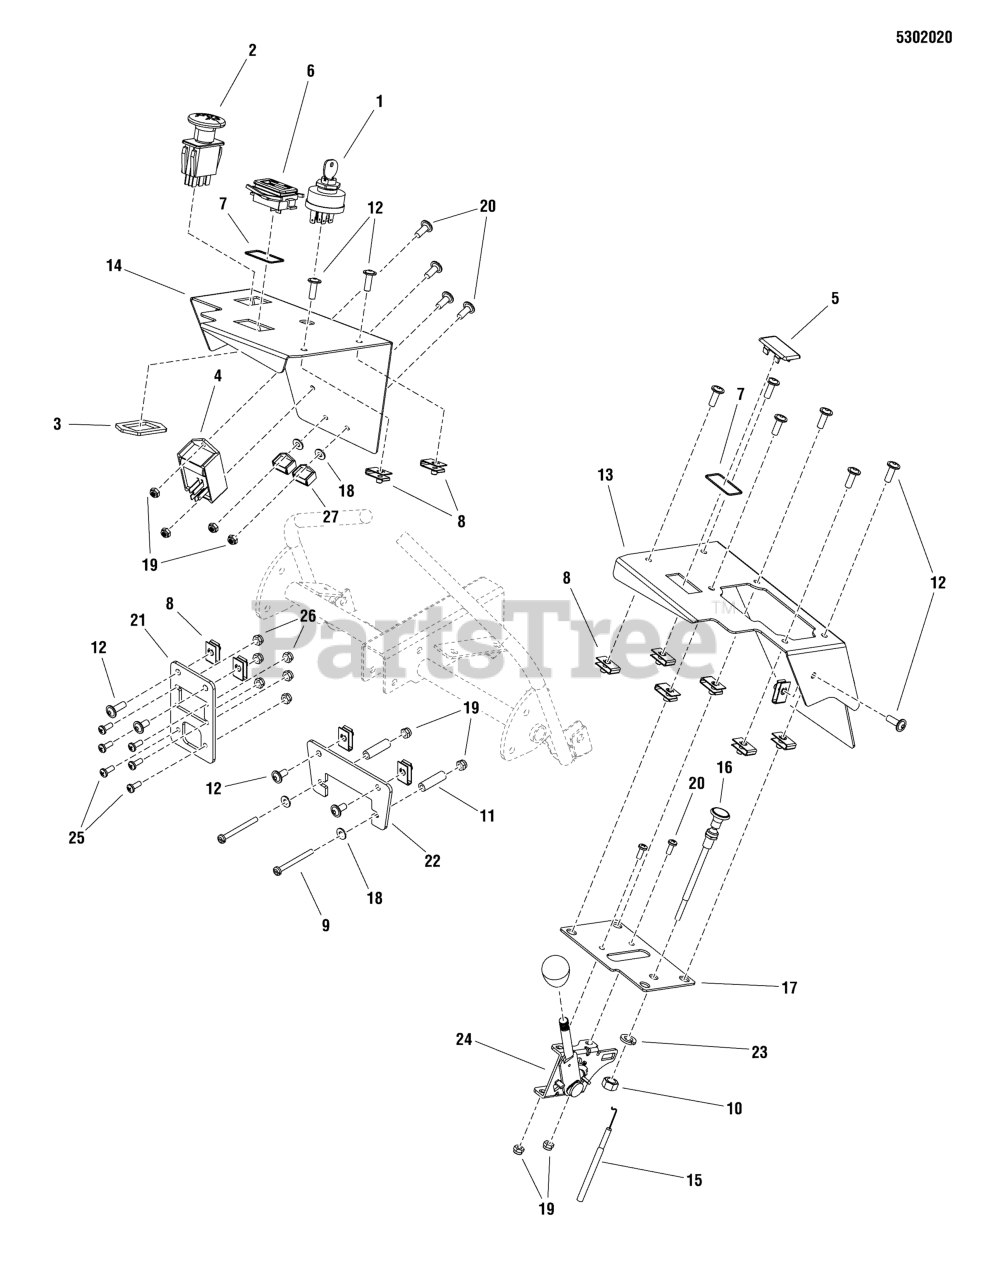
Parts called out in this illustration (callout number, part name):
1	SWITCH, IGNITION, 6 POST
2	SWITCH, BLADE ENGAGEMENT
3	RING, SWITCH RETAINER
4	MODULE, TIME DELAY
5	PLUG, .820X1.44 HOLE, BLACK PLASTIC
6	HOUR METER
7	O-RING, 7/8 ID X 1/16 W
8	BODY CLIP, 1/4-20 X 1/2 DEEP
9	SCREW, #10-24 X 2 ROUND PHILLIPS
10	NUT, 3/8-24 HEX JAM
11	SPACER, .20 X .38 X 1.25
13	PLATE, CONTROL PANEL, LH - RED
14	PLATE, CONTROL PANEL, RH - RED
15	CABLE, THROTTLE, 31"
16	CABLE, CHOKE CONTROL, 35.25"
17	PLATE, CHOKE/THROTTLE - RED
18	WASHER, #10 SAE
19	NUT, #10-24 HEX NYLON LOCK
20	SCREW- #10-24 X 1/2 ROUND PHILLIPS
21	PLATE, CONNECTORS, OPERATOR PLATFORM
22	PLATE, FUSE BLOCK - RED
23	WASHER, 3/8 SPLIT LOCK
24	LEVER, THROTTLE CONTROL
25	SCREW,#8-32 X 5/8 PHILLIPS ZP
26	NUT, #8-32 HEX NYLON LOCK
27	RELAY, 12V, 40A
